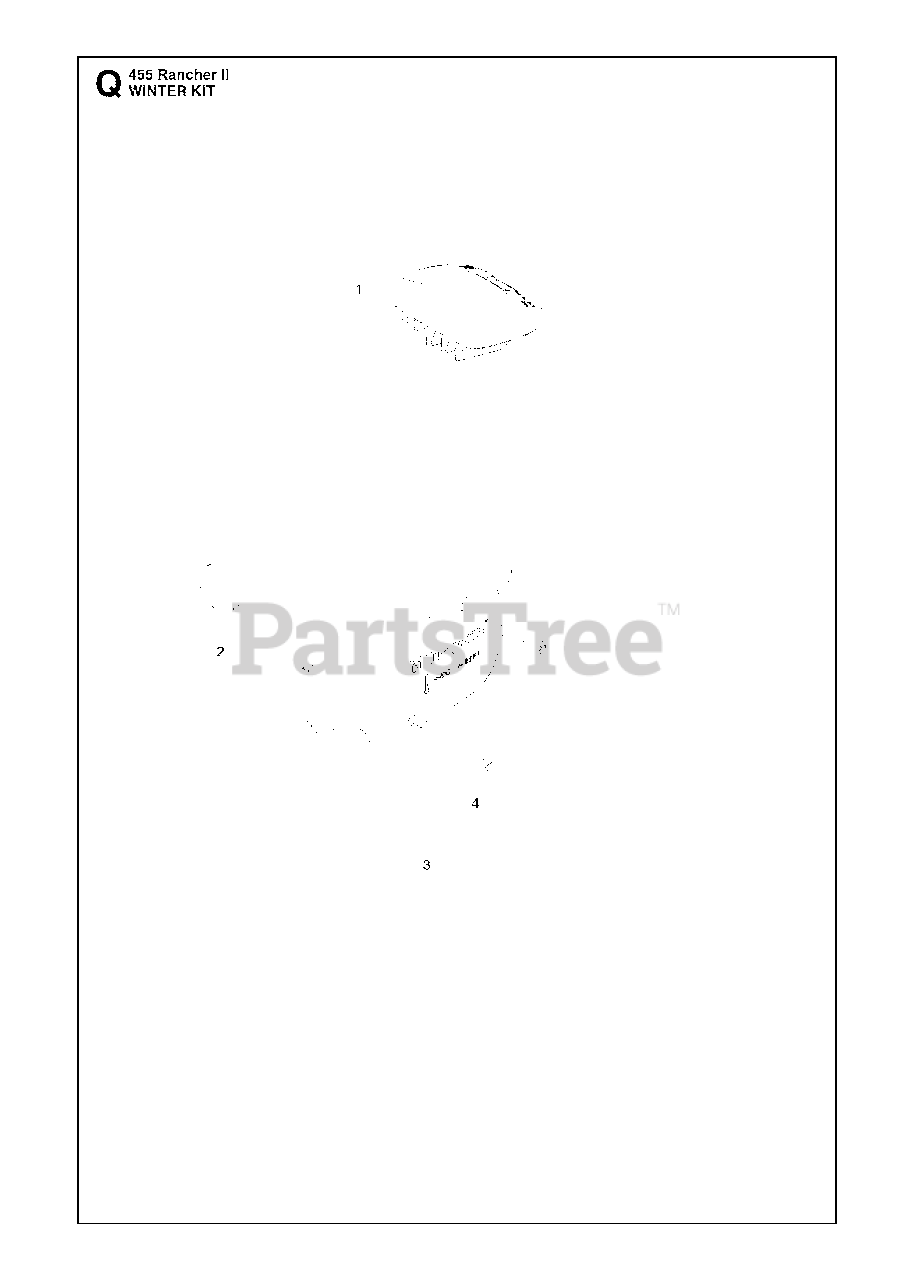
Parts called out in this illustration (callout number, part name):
1	AIR FILTER ASSY
2	PLUG
3	WINTER KIT
4	SCREW
